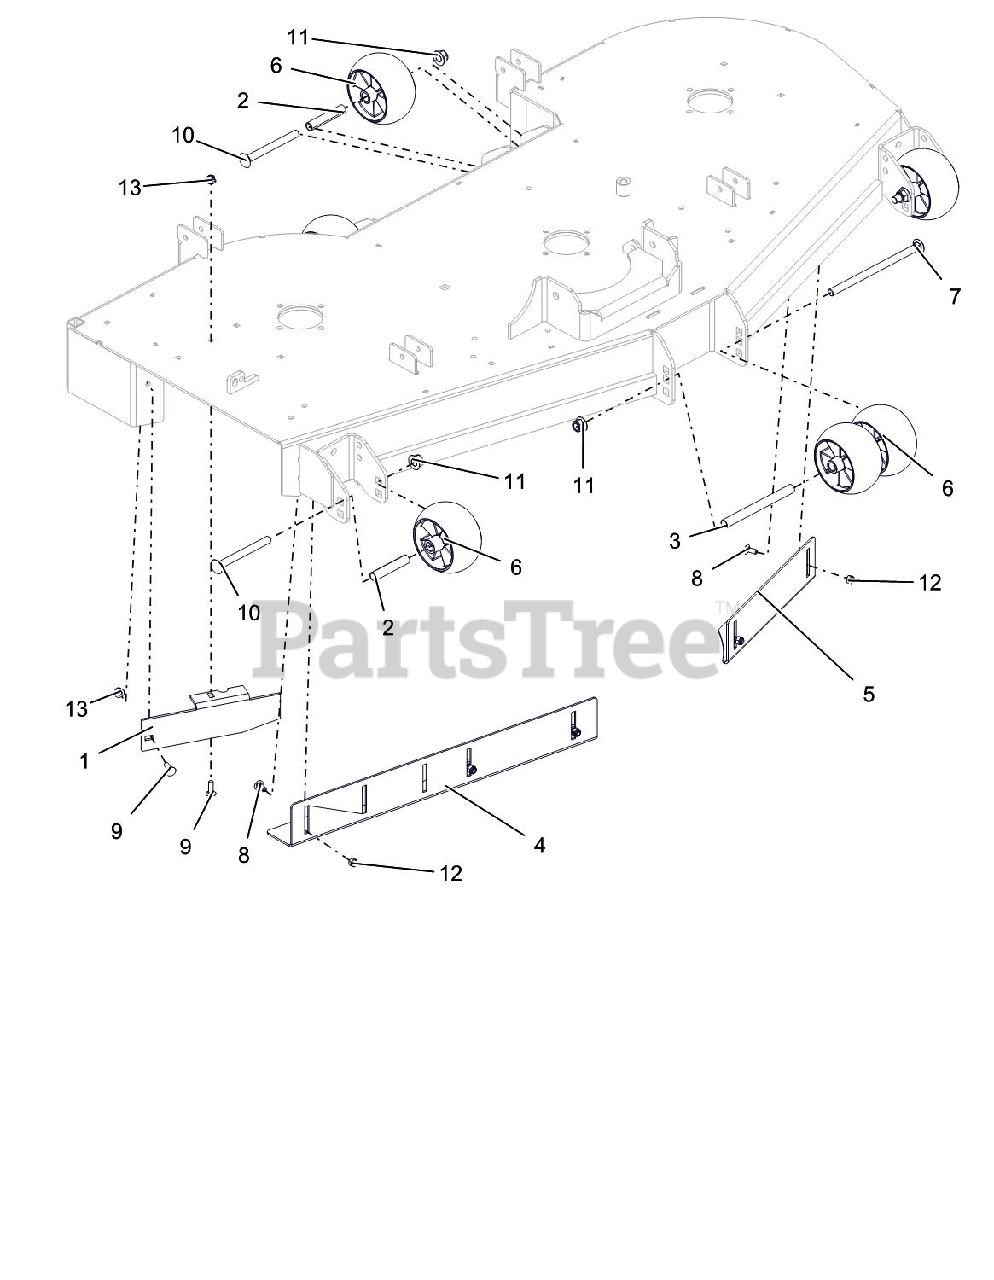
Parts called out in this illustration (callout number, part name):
1	60" DISCHARGE BAFFLE - RED
2	.510X.625X3.35 SPACER-LOW FILM
3	.510X.625X6.50 SPACER-LOW FILM
4	60" RH VACUUM BAFFLE - BLK
5	60" LH VACUUM BAFFLE - BLK
6	ANTI-SCALP WHEEL - 5X3 CTR
7	BLT-RDHDSQNK .50-13X8.50 G5YZ
8	BLT-RDHDSQNK .31-18X.75 G5YZ
9	BLT-RDHDSQNK .31-18X1.00 G5YZ
10	BLT-RDHDSQNK .50-13X5.00 GR5YZ
11	NUT-LK-NYL-FLG .50-13 YWZC
12	NUT-LK-NYL .312-18 YWZC
13	NUT-LK-NYL-FLG .31-18 YWZC
